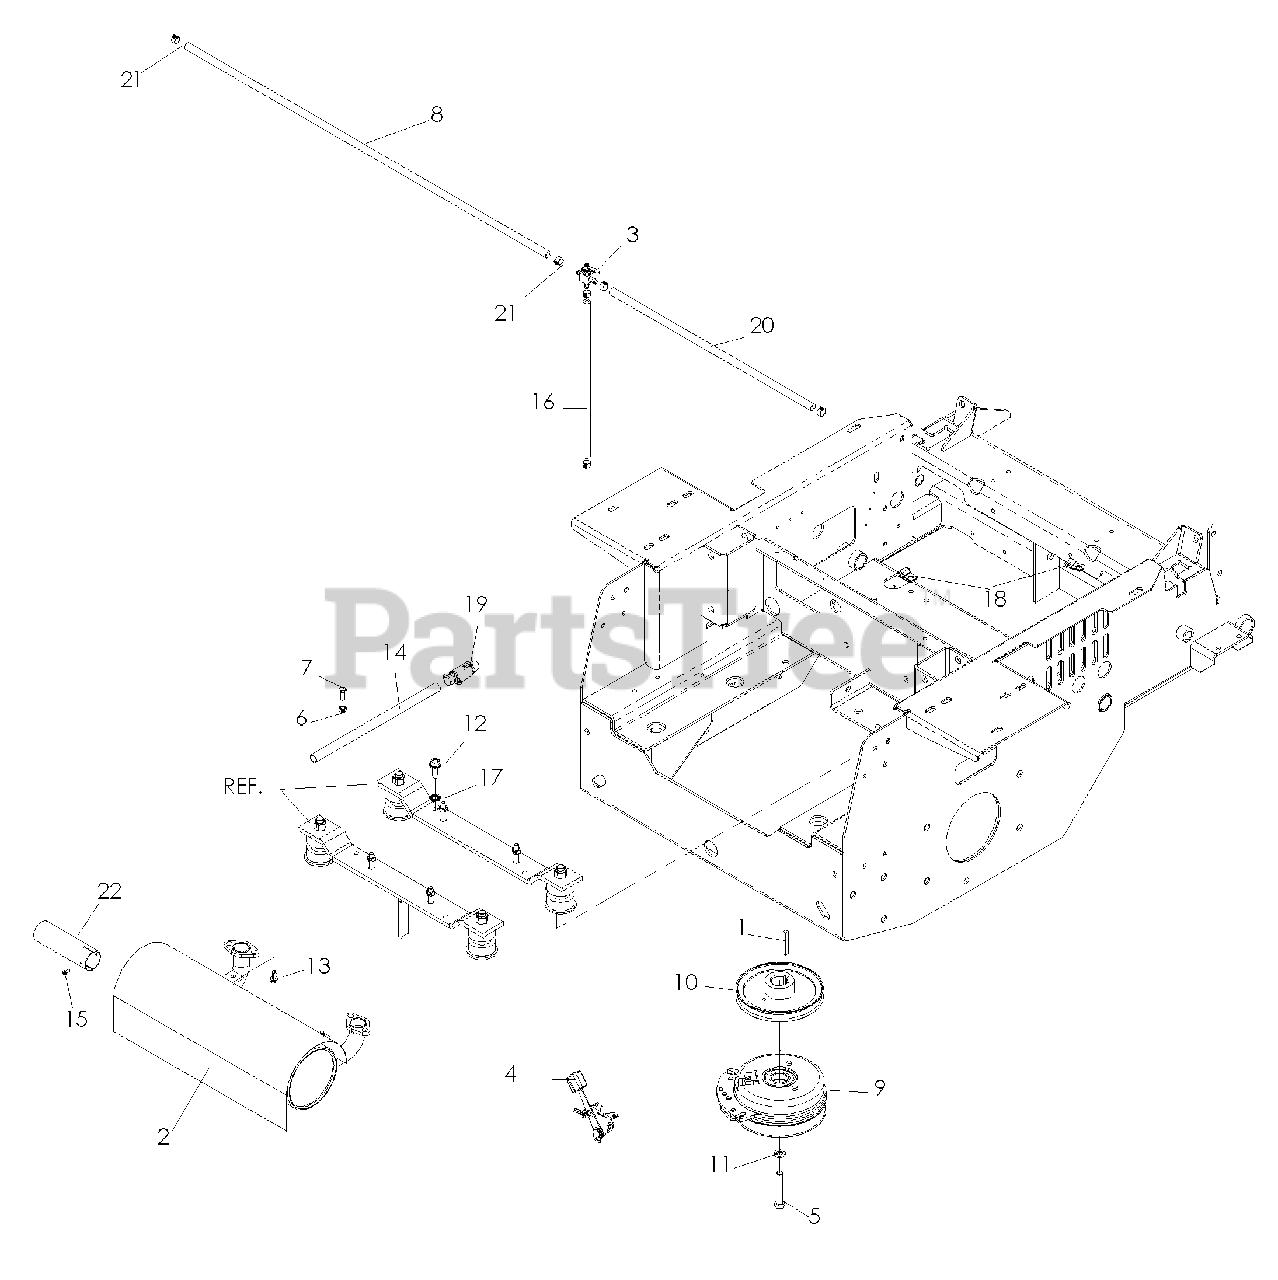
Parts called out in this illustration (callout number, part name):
1	KEY 1/4" SQ X 1 7/8"
2	MUFFLER
3	FUEL VALVE
4	CHOKE CABLE
5	BOLT 7/16F X 2 1/2
6	NUT 1/4C CENTER LOCK
7	HCS 1/4C X 3/4 HCS
8	HOSE 35"
9	ELECTRIC CLUTCH W/CABLE
11	WASHER 7/16 LOCK
12	BOLT 3/8-16 X 1.0
13	SCREW- 1/4-20 X 5/8
14	OIL DRAIN HOSE
15	SCR #8 X 1/2 PHIL HD DRILL BLK
16	FUEL LINE 13"
17	WASHER 3/8 EXT STAR ZD
18	DOUBLE TUBE CLAMP
19	OIL DRAIN FITTING
20	FUEL LINE
21	HOSE CLAMP
22	TUBE, EXTENSION, MUFFLER
